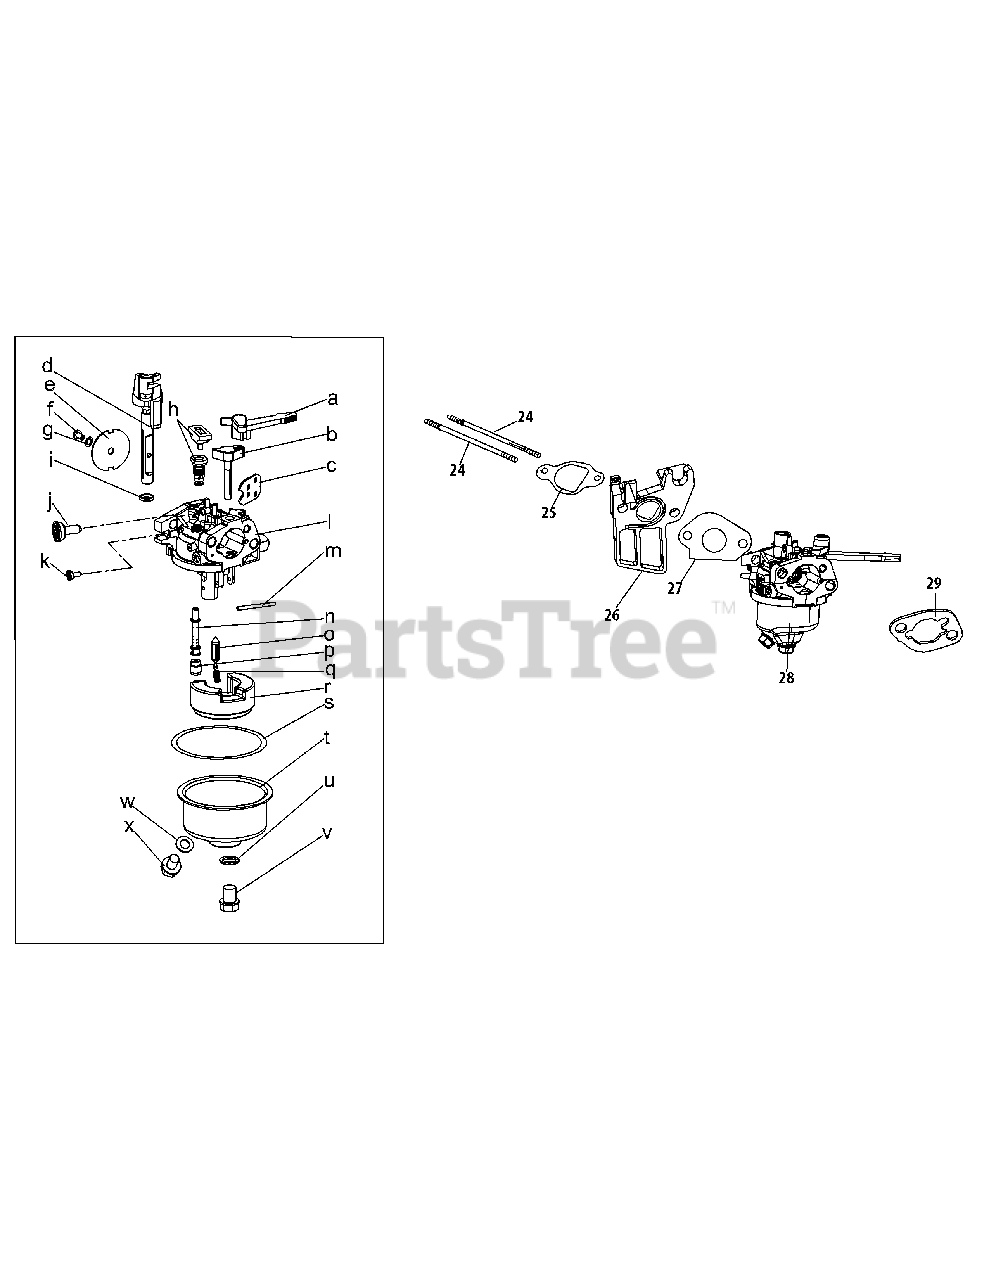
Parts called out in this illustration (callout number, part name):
24	Stud M6×110
25	Carburetor Insulator Gasket
26	Carburetor Insulator
27	Carburetor Gasket
28	Carburetor Assembly
29	Carburetor Gasket Plate
